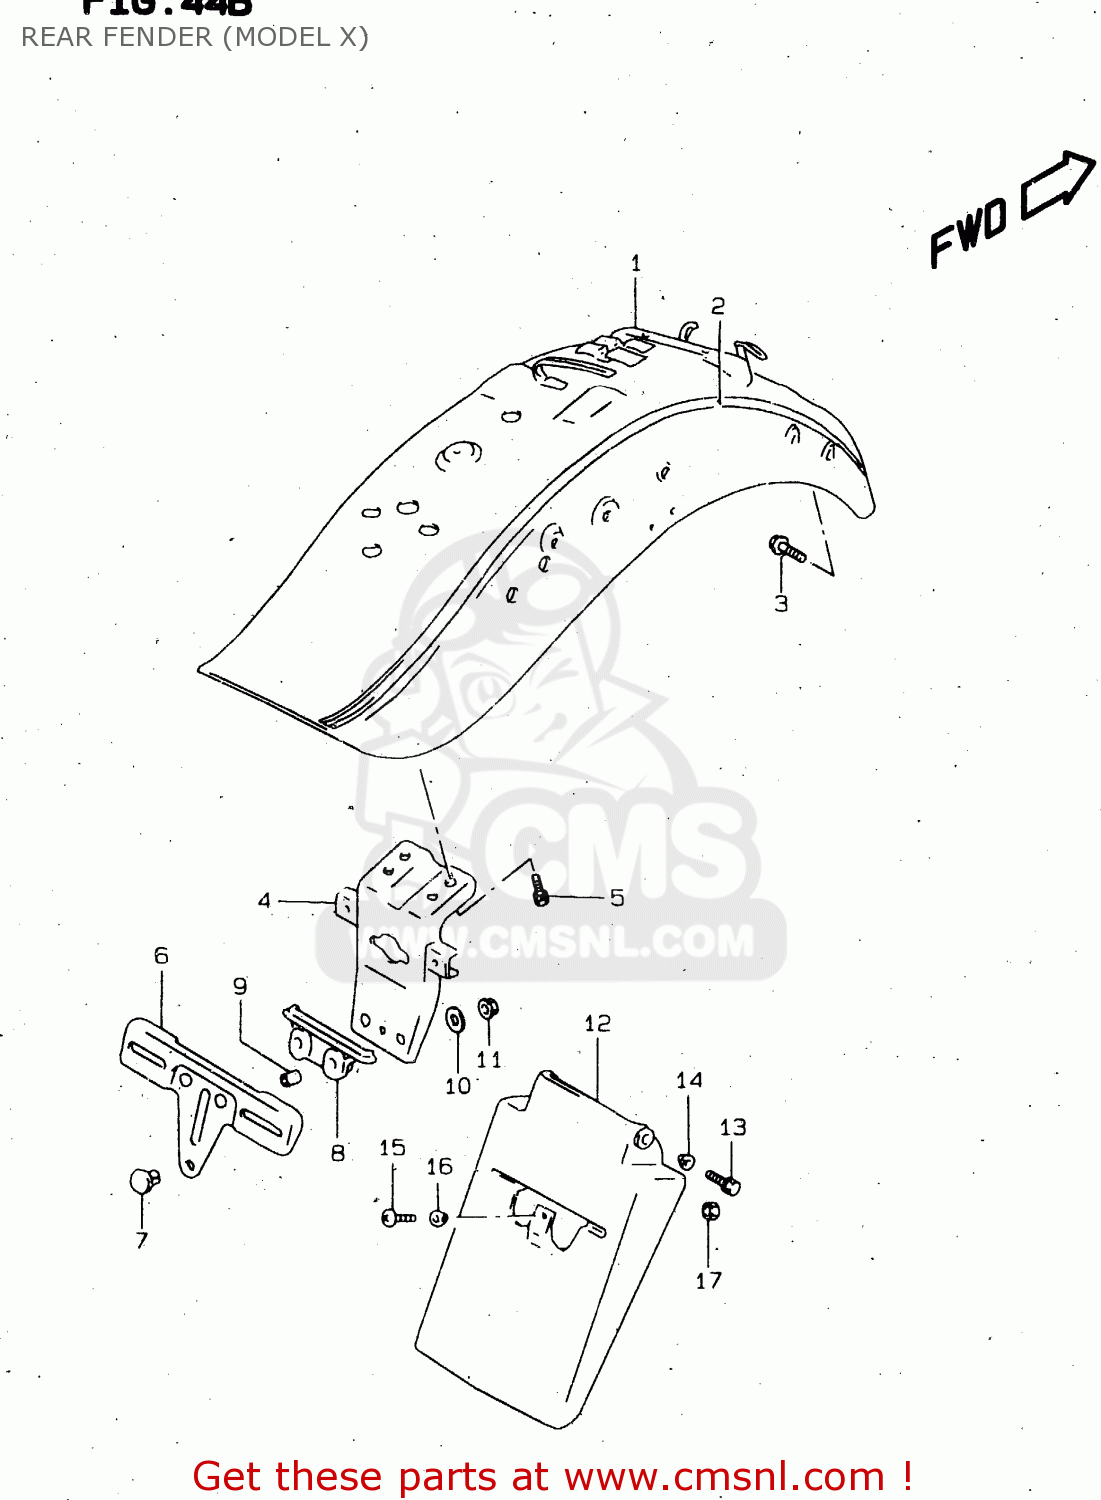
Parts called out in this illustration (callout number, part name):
1	FENDER, REAR
2	TAPE SET,REAR FENDER S
3	BOLT
4	BRACKET,LICENSE LAMP
5	BOLT
6	PLATE,REAR LICENSE
7	CUSHION
8	CUSHION,RR LICENSE PLATE
9	SPACER(5.5X8X14.3)
10	WASHER(5.5X20X1.2)
11	NUT
12	EXTENSION,RR FENDER
13	BOLT
14	WASHER
15	SCREW
16	WASHER
17	NUT 6MM
